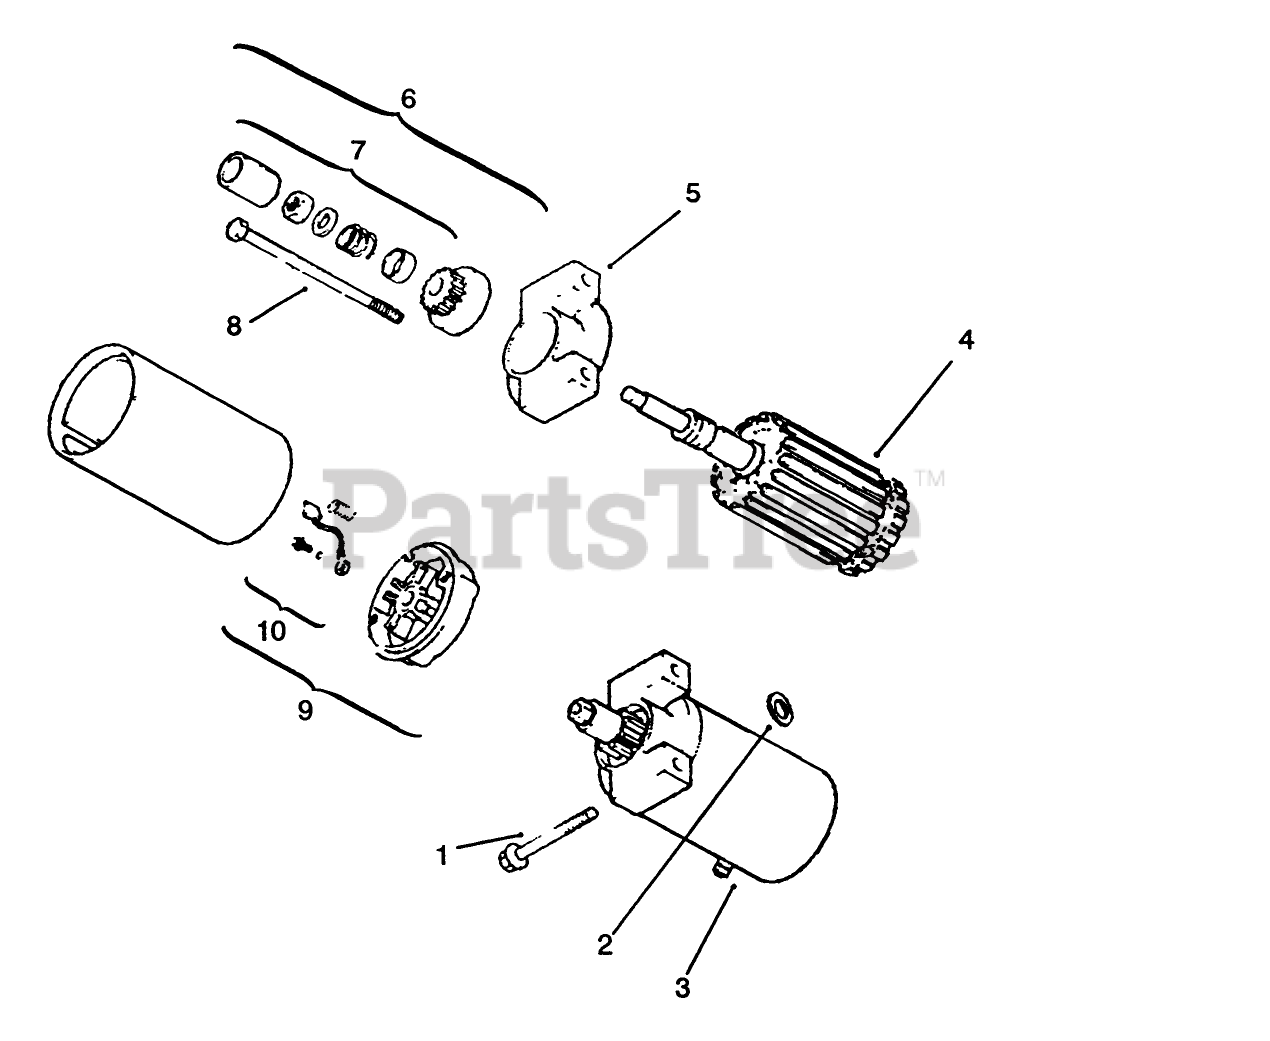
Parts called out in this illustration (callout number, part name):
1	Screw M8x1.25x70 (Only On: 72042, 72063, 72062, 72043)
2	Washer (Only On: 72042, 72063, 72062, 72043)
3	Starter ASM INC 4-10 (Only On: 72042, 72063, 72062, 72043)
4	Armature (Only On: 72042, 72063, 72062, 72043)
5	Cap-Drive End (Only On: 72042, 72063, 72062, 72043)
6	Kit-Drive INC 7 (Only On: 72042, 72063, 72062, 72043)
7	Kit-Drive Parts (Only On: 72042, 72063, 72062, 72043)
8	Screw-HF (Only On: 72042, 72063, 72062, 72043)
9	Cap-Commutator INC 10 (Only On: 72042, 72063, 72062, 72043)
10	Kit-Brush And Spring (Only On: 72042, 72063, 72062, 72043)
